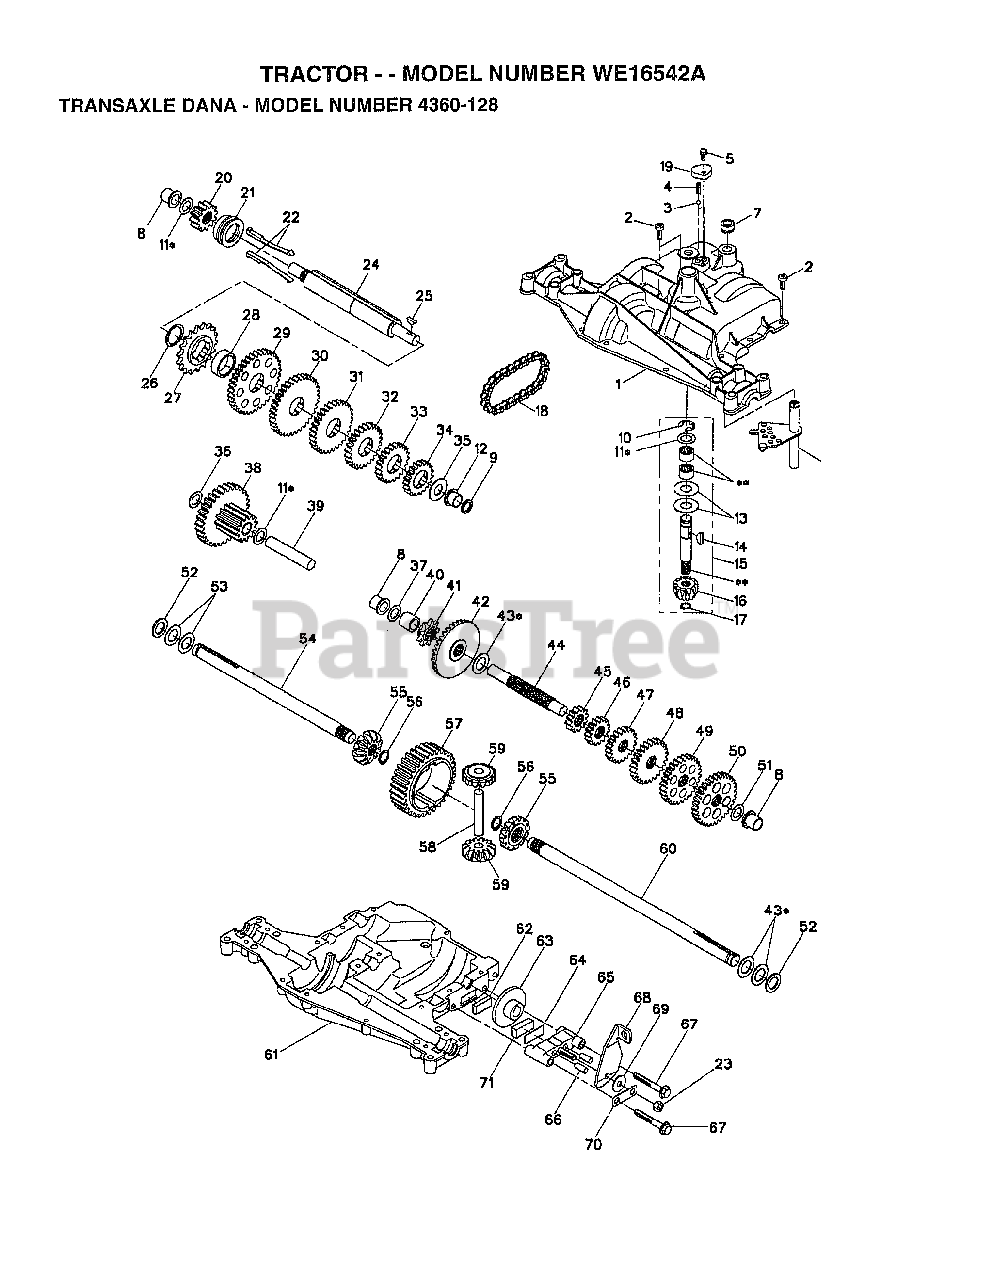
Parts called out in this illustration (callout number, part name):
1	HOUSING.UPPER(5305-P)
4	"SPRING, DETENT LT"
5	SCREW.TAPPING.1/4-20X.734
6	KIT SHIFTER ASM
9	SEAL.OIL.DAN.5508
10	RETAINING RING LT
11	ASM KIT SHIM 4689
12	BEARING.FLNG.5511
13	WASHER T
14	KEY WOODRUFF-DANA
15	INPUT SHAFT KIT 6250
16	PINION.BEVEL.12T(5620)
17	"RING,RETAINING LT"
18	"CHAIN,24 PTCH LT"
19	COVER.DETENT.(5584)
20	GEAR.SPUR.12T.(5627)
21	CLUTCH.COL.5467
22	ASM KIT CLTCH KEY
23	NUT.LOCK.5/16-24
24	SHAFT INTERM DANA
25	WOODRUFF KEY
26	"RING,RETAINING LT"
27	SPROCKET 18T T
28	SPACER YT
29	GEAR SPUR 37 TTH
30	GEAR SPUR 35 TTH
31	GEAR SPUR 30T
32	GEAR 25T LT
33	GEAR SPUR 22 TT
34	SPUR GEAR 19T
35	"WASHER, PLAIN LT"
36	WASHER 045
37	WASHER 031
38	ASSY.GEAR.6153 12T&30T
39	SHAFT IDLER
40	SPACER T
41	SPROCKET 9T LT
42	GEAR.BEVEL.36T(5621)
43	ASM KIT SHIM
44	SHAFT T
45	GEAR SPUR 12 TTH
47	GEAR SPUR 20T
48	"GEAR, SPUR 25T LT"
49	GEAR 28T T
50	"GEAR, SPUR 31T LT"
51	WASHER 060
52	NEOPRENE WASHER
53	WASHER 031
54	AXLE.LH(5528-1)
55	MITER 5270 12T.SPLINED
56	RING.RETAINING.(5270)
58	SHAFT T
59	MITER 5623.12T.IDLER
60	AXLE.RH.(5528-2) DANA
61	HOUSING.KIT (6088)
62	PUCK T
63	BRAKE DISC. T
64	SPACER LT
66	PIN T
67	SCREW.(5562) .5/16-18X2.35
69	WASHER LT
70	BRACKET, ANTI-ROTATION
71	PUCK T
